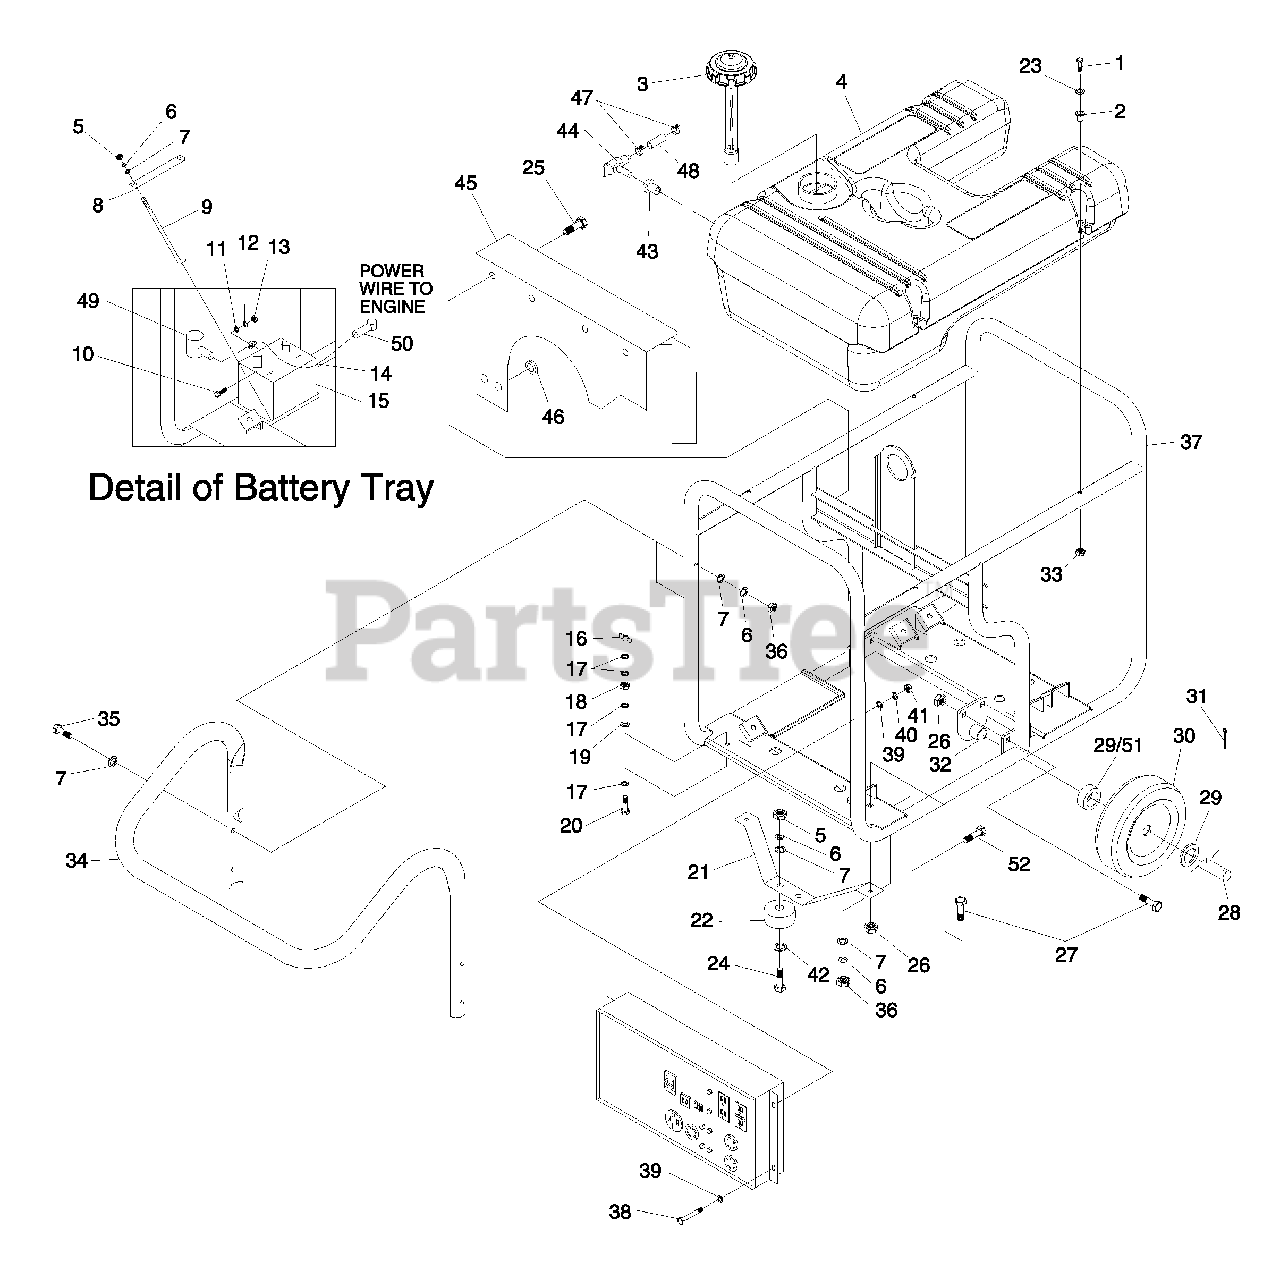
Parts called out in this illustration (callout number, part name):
1	SCREW HHC M6-1.0 X 55
2	RUBBER TANK MOUNT
3	CAP, FUEL WITH GAUGE & VENT
4	KIT, FUEL TANK
5	NUT HEX M8-1.25
6	WASHER LOCK M8-5/16
7	WASHER FLAT 5/16
8	BRACKET BATTERY
9	BOLT,BATTERY J-BOLT
10	SCREW HHC 1/4-20 X 3/4 G5
11	WASHER FLAT 1/4
12	WASHER LOCK M6-1/4
13	NUT HEX 1/4-20
14	BATTERY CABLE, RED
15	BATTERY U1
16	NUT WING 5/16-18 BRASS
17	WASHER FLAT 5/16 BRASS
18	NUT HEX 5/16-18 BRASS
19	5/16 SPECIAL L/WASH
20	SCREW HHC 5/16-18 X 1.5 BRASS
21	BRACKET FRONT FOOT (15 kW)
22	VIB MOUNT
23	WASHER FLAT .25ID X 1"OD
24	SCREW HHC M8-1.25 X 30
25	SCREW HHTT M6-1.0 X 12
26	NUT LOCK FL 3/8-16
27	BOLT CARR 3/8-16 X 1
28	AXLE, 3/4"DIA X 30" (15 kW)
29	WASHER FLAT 3/4" (15 kW)
30	12.3" PNEUM WHEEL 3/4" AXLE (15 kW)
31	PIN COTTER 1/8 X 1-1/4
32	BRACKET, WHEEL SPACER
33	NUT FLANGE M6-1.0 NYLOK
35	SCREW HHC 5/16-18 X 2-1/2 G5
36	NUT LOCK HEX 5/16-18 NYLON INSERT
37	FRAME
38	SCREW HHC M5-0.8 X 45 G8.8
39	WASHER FLAT M5
40	WASHER LOCK M5
41	NUT HEX M5-0.8
42	WASHER FLAT 1"
43	BUSHING TANK DEXTOR
44	VALVE, PLASTIC TANK
45	AIR DEFLECTOR
46	GROMMET .75 X .06 X .50
47	CLAMP HOSE BAND1/4
48	HOSE1/4 ID
49	BOOT BATTERY CABLE
50	BOOT STARTER CABLE
51	SPACER, AXLE (15 kW)
52	SCREW HHC 5/16"-18 X 1"
